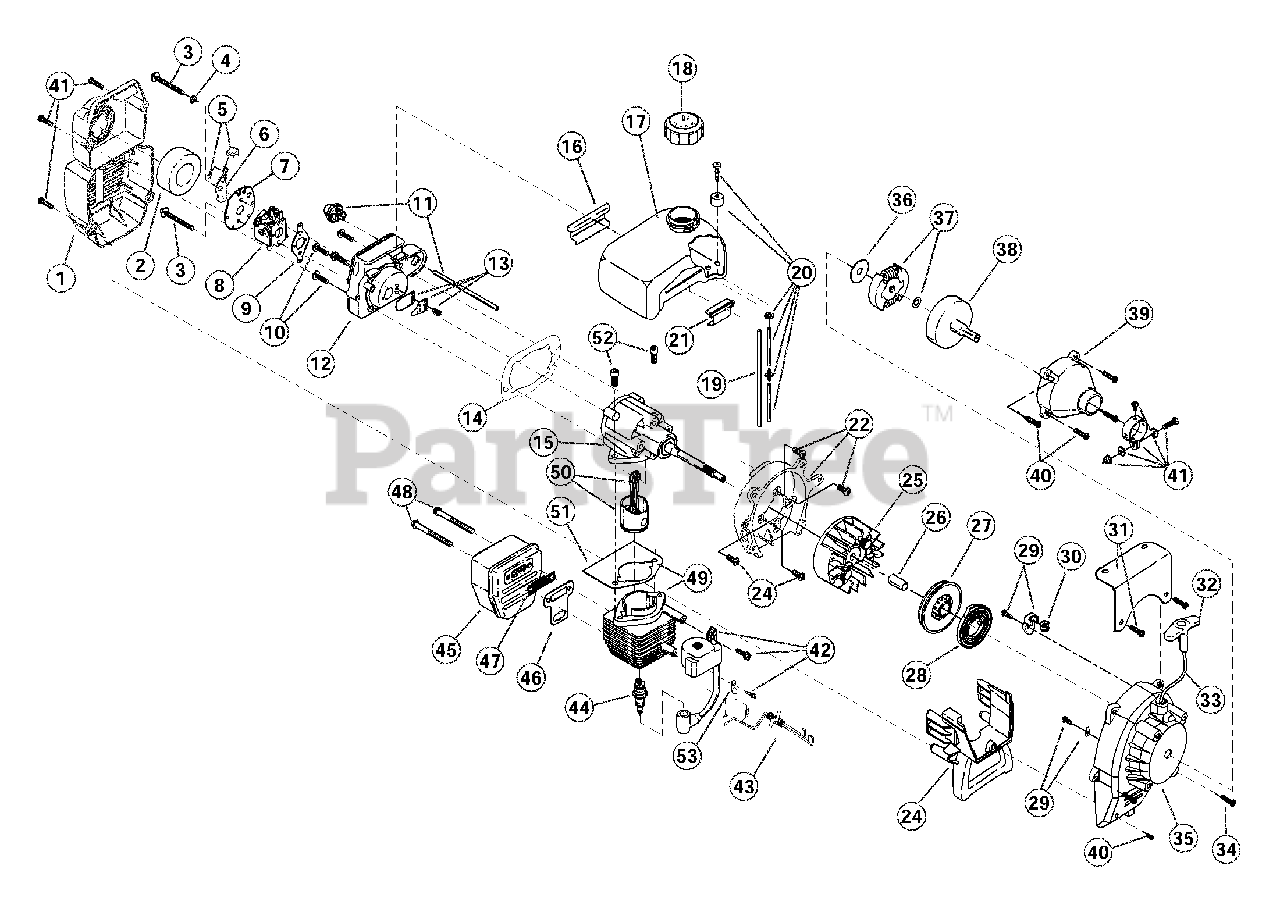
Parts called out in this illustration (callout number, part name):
1	Air Cleaner/Muffler Cover Assembly includes 2 & 40)
2	Air Cleaner Filter
3	Carburetor Mounting Screw Assembly
4	Wavey Washer
5	Choke Knob & Screw
6	Choke Lever Assembly (includes 5)
7	Choke Lever & Plate (includes 6)
8	Carburetor Assembly (includes 9 & 20)
9	Carburetor Gasket
10	Carb Mount Screw
11	Primer and Hose Assembly
12	Carb Mount Assembly (includes 10 & 13)
13	Reed Assembly
14	Carburetor Mount Gasket
15	Crank Case Service Assembly (includes 10 & 23)
16	Rear Mounting Pad
17	Fuel Tank Assembly (includes 18-20)
18	Fuel Cap Assembly
19	Fuel Return Line
20	Fuel Line Assembly
21	Front Mounting Pad
22	Shroud Assembly
23	Shroud Screw
24	Shroud Extension and Stand (includes 40)
25	Flywheel Assembly
27	Recoil Pulley Assembly
28	Recoil Spring
29	Pulley Retainer Assembly
30	Rope Guide
31	Fuel Tank Guard Assembly
32	Pull Handle
34	Housing Screw
35	Starter Housing Assembly (includes items 27-30, 32-34 & 40)
36	Clutch Washer
37	Clutch Rotor Assembly
38	Clutch Drum Assembly
39	Clutch Cover Assembly (includes 40)
40	Clutch Cover Screw
41	Upper Clamp Assembly
42	Module Assembly (includes 52)
43	Wire Lead
44	Spark Plug
45	Muffler Assembly (includes item 46-48)
46	Exhaust Gasket
47	Spark Arrestor
48	Muffler Mounting Bolt Assembly
49	Cylinder Assembly (includes items 51& 52)
50	Piston & Rod Assembly
51	Cylinder Gasket
52	Cylinder Bolt
53	Ground Tab
